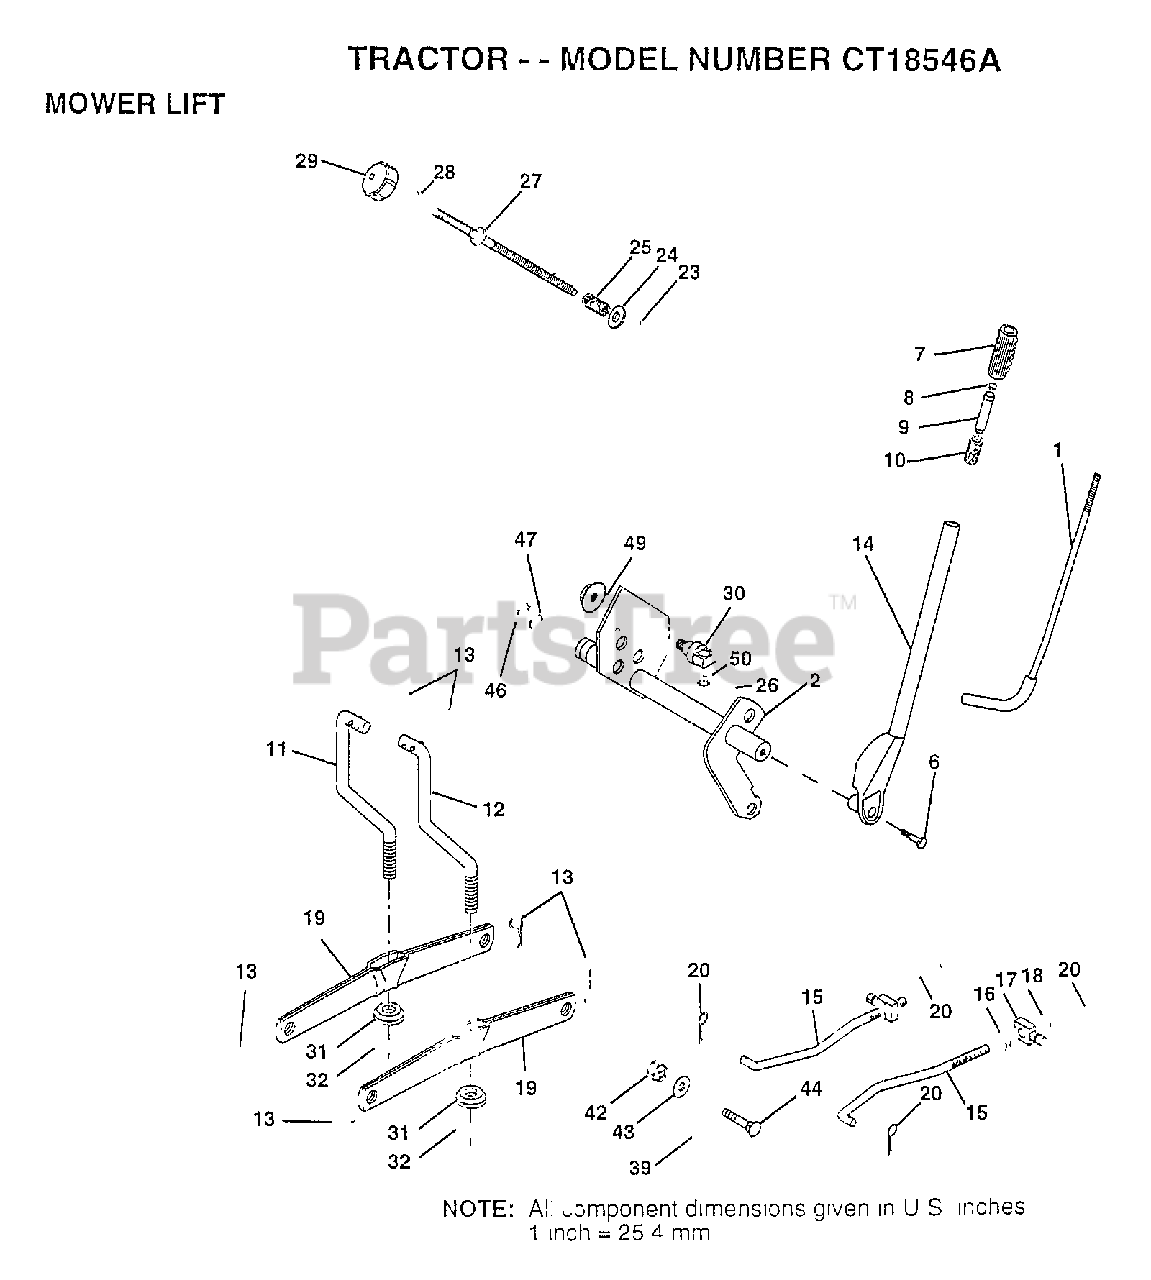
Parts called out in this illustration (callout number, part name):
1	LEVER ROD LT
2	SHAFT LIFT W/IND
6	"BOLT,HEX"
7	GRIP
10	SPRING T
11	LINK.LIFT.LH.GTV
12	LINK.LIFT.RH.GTV.
15	LINK.FRONT
16	NUT
17	TRUNION
18	NUT.LK.W/WSH.1/2.
19	ARM SUSP REAR
20	RETAINER.SPRING
23	NUT T
24	WASHER
25	SPRING.COMP.INF.H
27	ROD.ADJ.LIFT
28	NUT
29	KNOB INF 3/8-16
30	TRUNNION
31	BEARING PVT LH
32	NUT.CROWNLOCK.3/8
39	STOP.OVER.CENTER
43	WASHER GT
44	BOLT
46	E-RING
47	WASHER
49	NUT.HXFLG.LOCK.
50	NUT PUSH M
